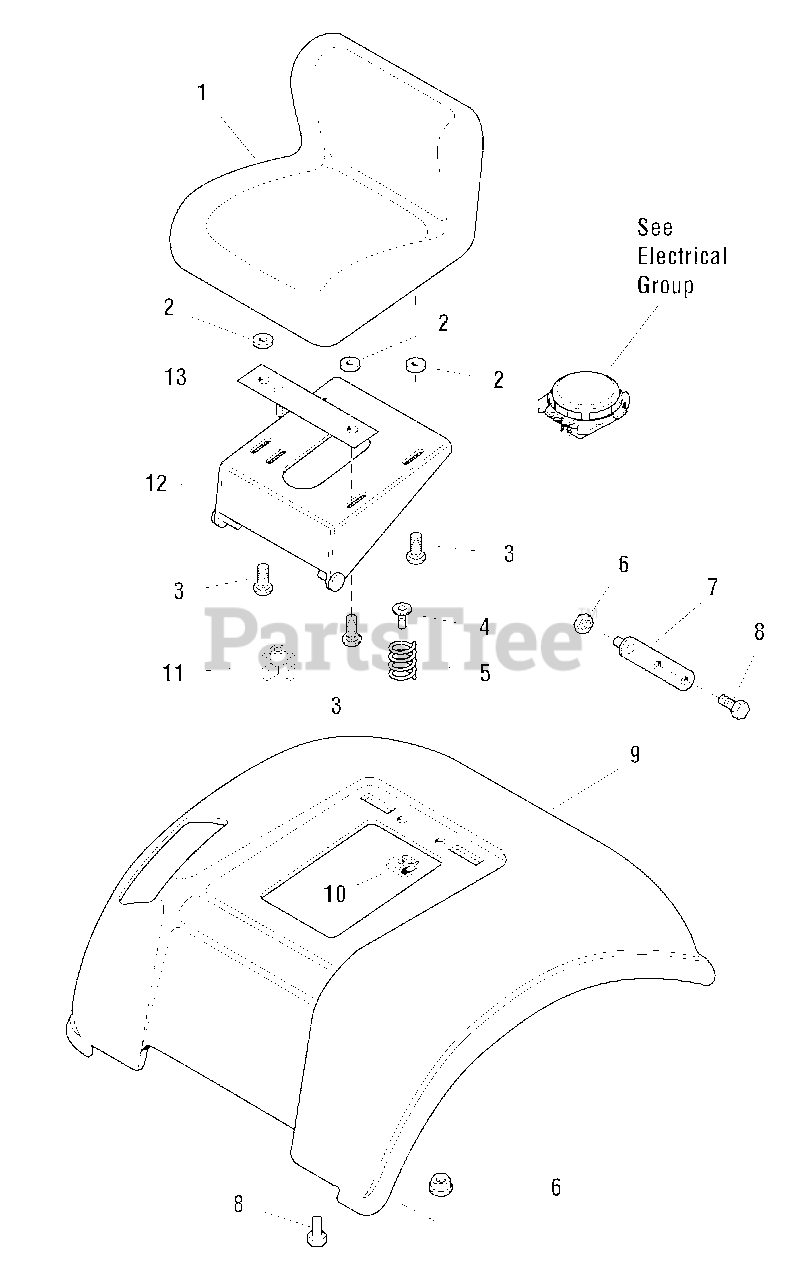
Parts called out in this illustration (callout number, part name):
2	WASHER
3	CARRIAGE BOLT, 5/16-18 x 3/4
4	SCREW, Flat Head, 5/16-18 x 1-1/4
5	SPRING, Compression
6	NUT, Hex Head Whiz Lock, 5/16-18
8	CAPSCREW, Hex Head Whiz Lock Flange, 5/16-18 x 3/4
9	DECK, Seat
10	NUT, Speed 5/16-18
12	SUPPORT & PIN ASSEMBLY
13	CLAMP & SCREW ASSEMBLY
